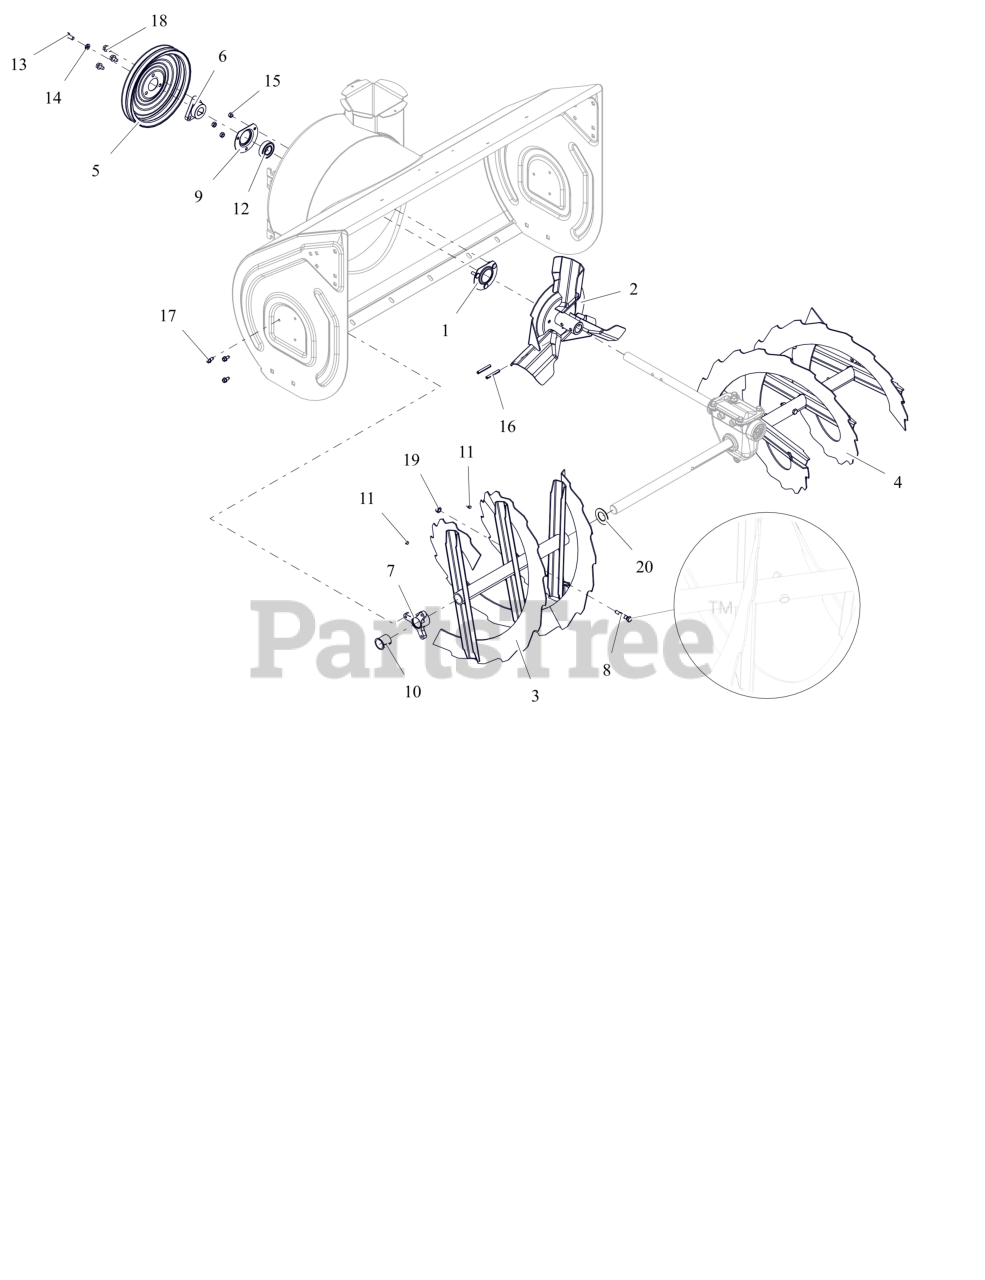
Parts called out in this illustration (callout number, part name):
1	BEARING FLANGE
2	IMPELLER, 3 BLADE-14"
3	RAKE, RH-36"(1 ID X 15.75 OD)
4	RAKE, LH-36" (1 ID X 15.75 OD)
5	PULLEY, SPIN FORM DUAL GROOVE
6	PULLEY HUB, D-BORE .87 PRO
7	BUSHING, RAKE SHAFT 1"
8	SHEAR BOLT SERVICE ASSEMBLY (INCLUDES NUT)
9	BEARING FLANGE
10	BSHG-FLG SPLIT NYLINER 1.0" HP
11	ZERK,FITTING .25X.125 DRIVE IN
12	BRG-BALL .876X1.75X.50 RSTFP
13	BLT, HEX .31-24X.750 G5 ZCC
14	WSHR, LK-HVY .312X.097 ZCC
15	NUT,LK-CTR .25-20 GA ZCC
16	PIN-ROLL .250X1.75
17	SCR-TAP .25-20X.50 HWH ZCC
18	SCR,TAP .312-18X.50 HWH TR ZCC
19	NUT,LK-CTR .31-18 GA ZCC
20	WSHR- FLT 1.010X1.755X.062 ZCC
